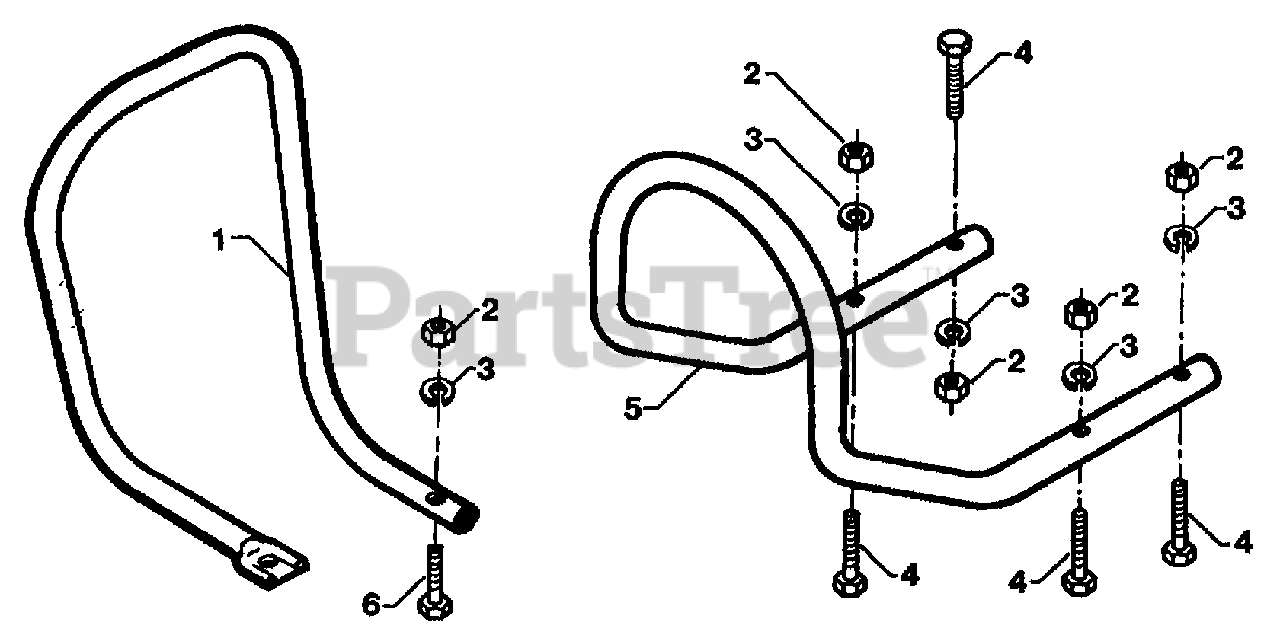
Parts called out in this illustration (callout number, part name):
1	GUARD-CARBURETOR PNT
2	NUT-HEX 5/16-18 ZP
3	WASHER-LK .312 ZP
4	SCR-HH 5/16-18X2.5
5	BUMPER-JR PNT
6	SCR-HH 5/16-18X1.5 G5 ZP
